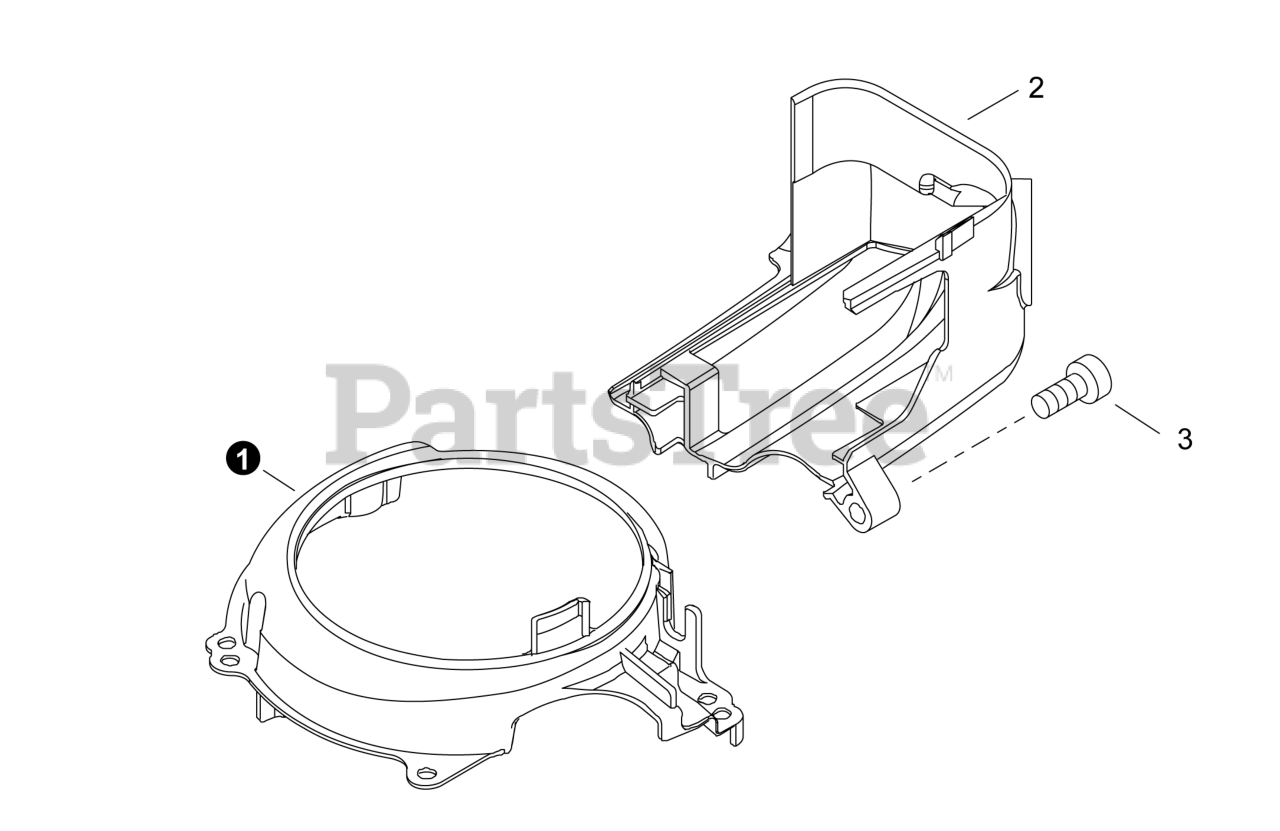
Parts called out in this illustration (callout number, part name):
1	COVER, FAN
2	COVER, ENGINE
3	BOLT, TORX 5x16
